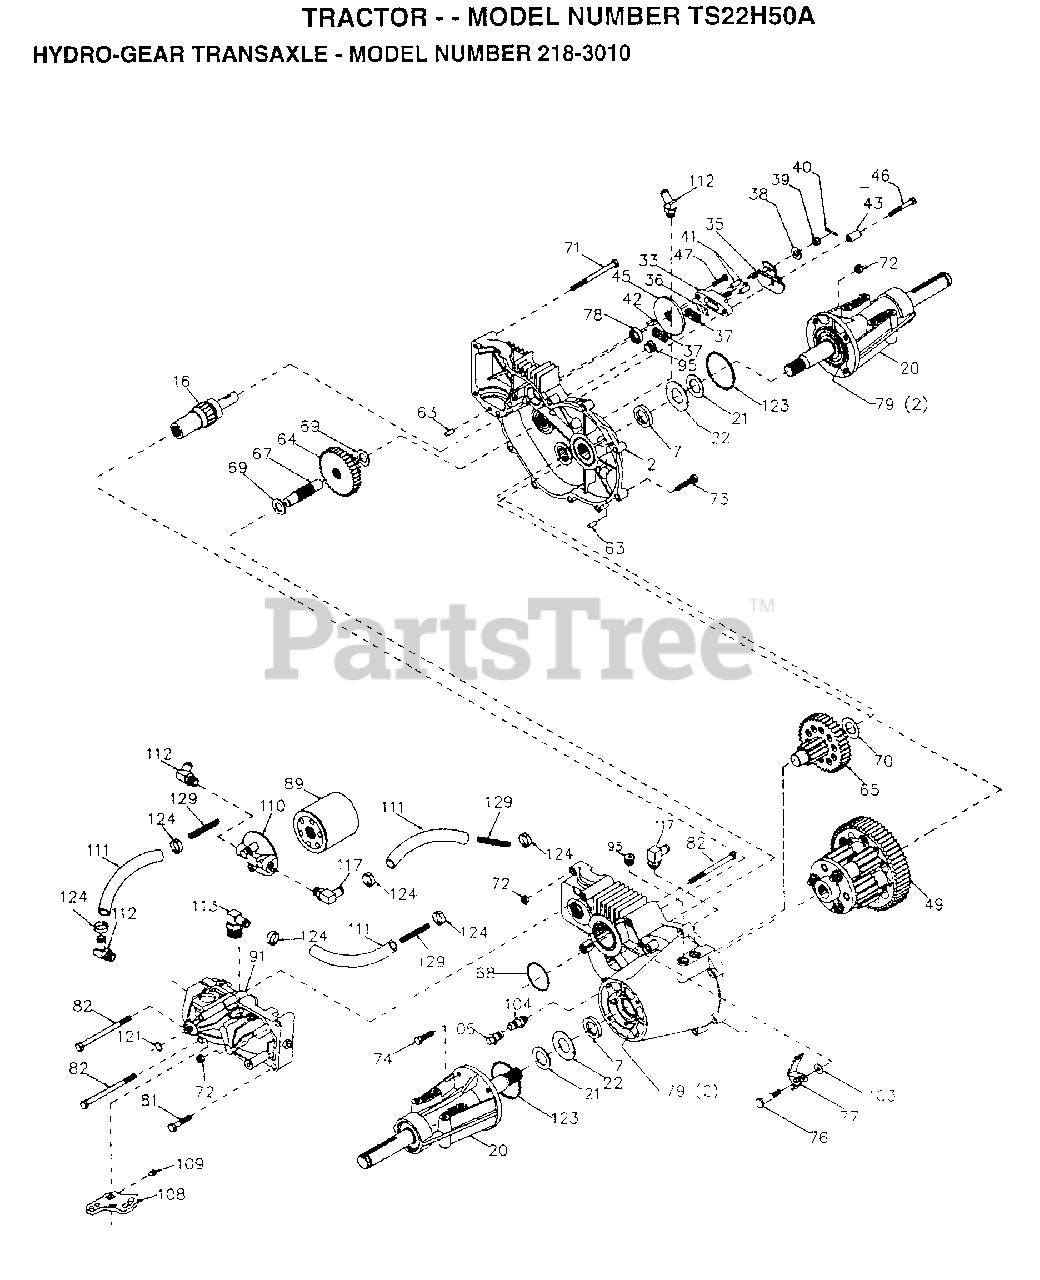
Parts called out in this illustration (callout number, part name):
1	HOUSING LH 70086
2	HOUSING RH 70088
7	SEAL.OIL.44782.HY
16	SHAFT BRAKE 62877
20	AXLE MTG 70087
21	WASHER 44805
22	WASHER 44806
33	YOKE.BRAKE.62589
35	ARM BRAKE 50214
36	PUCK PLATE 44134
37	PUCK BRAKE 44132
38	WASHER HYD 44130
41	PIN BRAKE 44127
42	KEY HI PRO 44143
43	SPACER 50259
45	DISC BRAKE 44090
46	BOLT 1/4-20 44276
47	BOLT 1/4-20 44433
49	DIFFRENTIAL.70251
63	PIN DOWL 44757
64	GEAR.14-38.44776
65	PINION DRIV 70051
67	SHAFT-44779
68	O RING 44781
69	WASHER 44795
70	WASHER 44794
71	BOLT 5/16 44827
72	LOCKNUT.43064
73	BOLT 5/16 44841
74	SCREW 5/16 45089
76	BOLT SHOULD 44785
77	ARM FREEWHL 44786
78	SEAL.OIL.44761
81	BOLT 5/16 43084
82	BOLT 5/16 44820
89	FILTER SPIN 50037
91	PUMP.BDU-10L-122
95	PLUG.9005110-5600
96	FITTING.SAE.50257
103	WASHER.50169
104	CAP.VENT.70109
106	O-RING.ASM.70110
108	ARM.CONTROL.45007
109	SCREW.SET.50018.
110	FILTER.HEAD.50207
111	HOSE.50632
112	FITTING.SAE.50604
113	FITTING.SAE.50592
117	FITTING.SAE.50589
123	O-RING.50405
124	CLAMP.50590
129	SPRING.LONG.50667
